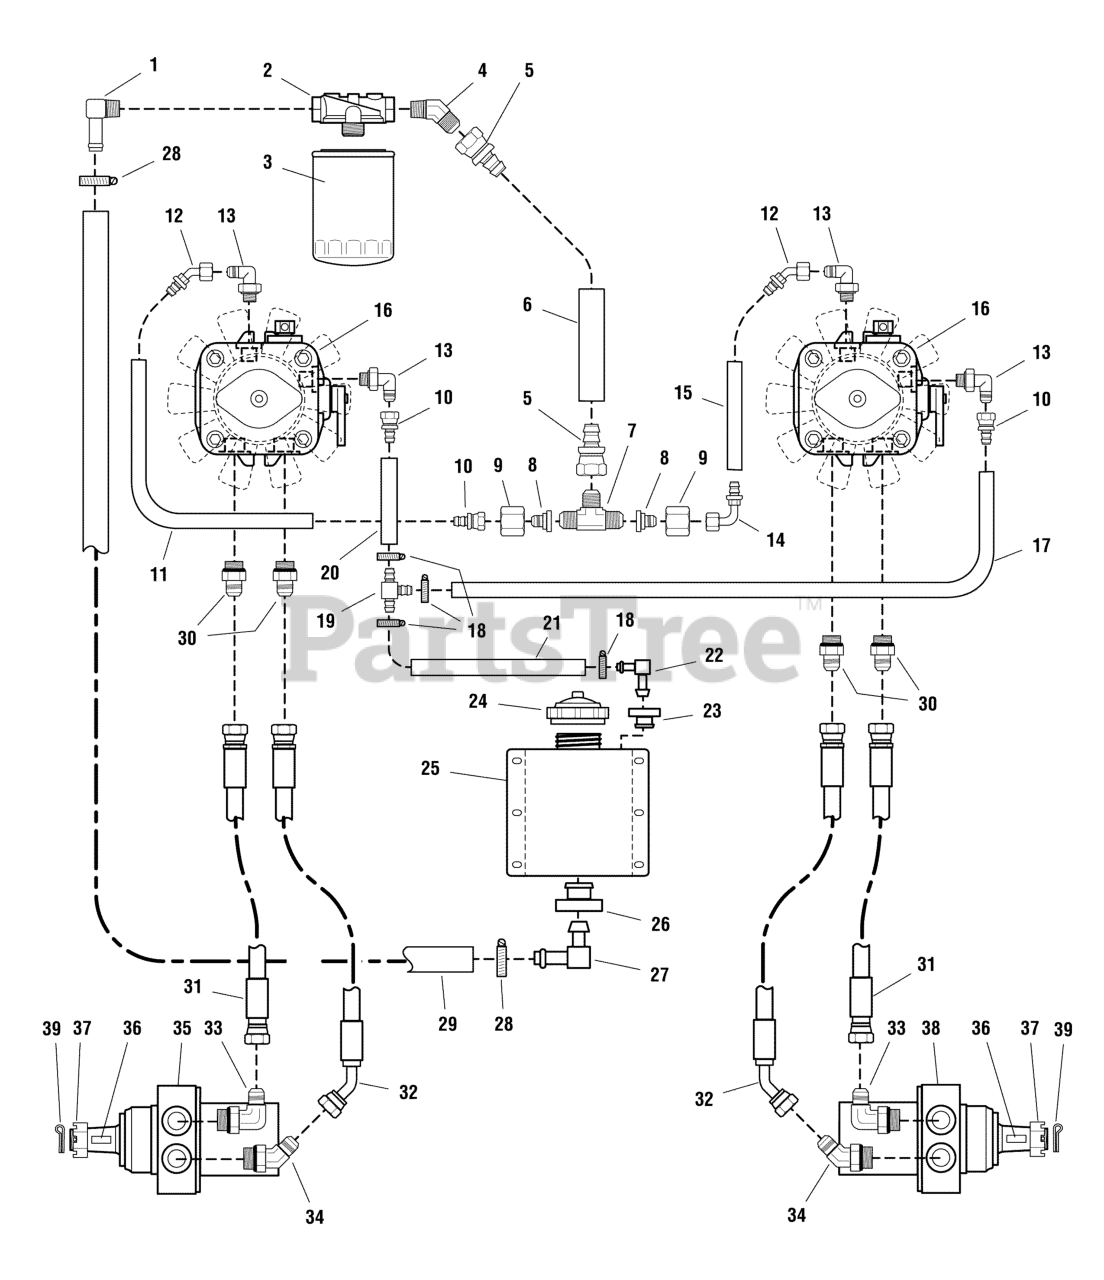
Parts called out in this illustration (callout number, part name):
1	FITTING, 1/2" NPT, 90 Deg.
2	FILTER HEAD
3	FILTER, HYDRAULIC, SERVICE PART (PKG)
4	FITTING, 1/2" NPT, 45 Deg.
5	FITTING, Straight Swivel
6	HOSE, Hydraulic, 7-1/2"
7	FITTING, Tee
8	ADAPTER, Tee
9	NUT, Adapter
10	FITTING, Straight Swivel
11	HOSE, Hydraulic, 13-3/4"
12	FITTING, 45 Deg. Swivel
13	FITTING, O-Ring, 90 Deg.
14	FITTING, 90 Deg. Swivel
15	HOSE, Hydraulic, 6-3/4"
16	HYDRAULIC PUMP, 10CC, w/ FAN
16	HUB & FAN KIT
17	HOSE, Hydraulic, 16-1/2"
18	CLAMP, #6 Hose
19	FITTING, TEE, 3/8" Hose
20	HOSE, Hydraulic, 6"
21	HOSE, Hydraulic, 26-1/4"
22	FITTING, Elbow, 3/8"
23	GROMMET
24	CAP, Hydraulic Oil Only
25	HYDRAULIC OIL RESERVOIR, Complete
26	GROMMET
27	FITTING, Elbow, 5/8"
28	CLAMP, #10 Hose
29	HOSE, Hydraulic, 19"
30	FITTING, O-Ring Adapter
31	HOSE ASSEMBLY 16.75, HP, ST X ST
32	HYDRAULIC HOSE ASSEMBLY, 22"
33	FITTING, O-Ring, 90 Deg.
34	FITTING, O-Ring, 45 Deg.
35	HYDRAULIC WHEEL MOTOR-LEFT, Complete
36	KEY
37	NUT, CASTLE, 1-20
38	HYDRAULIC WHEEL MOTOR-RIGHT, Complete
39	PIN, COTTER, 1/8" X 2"
